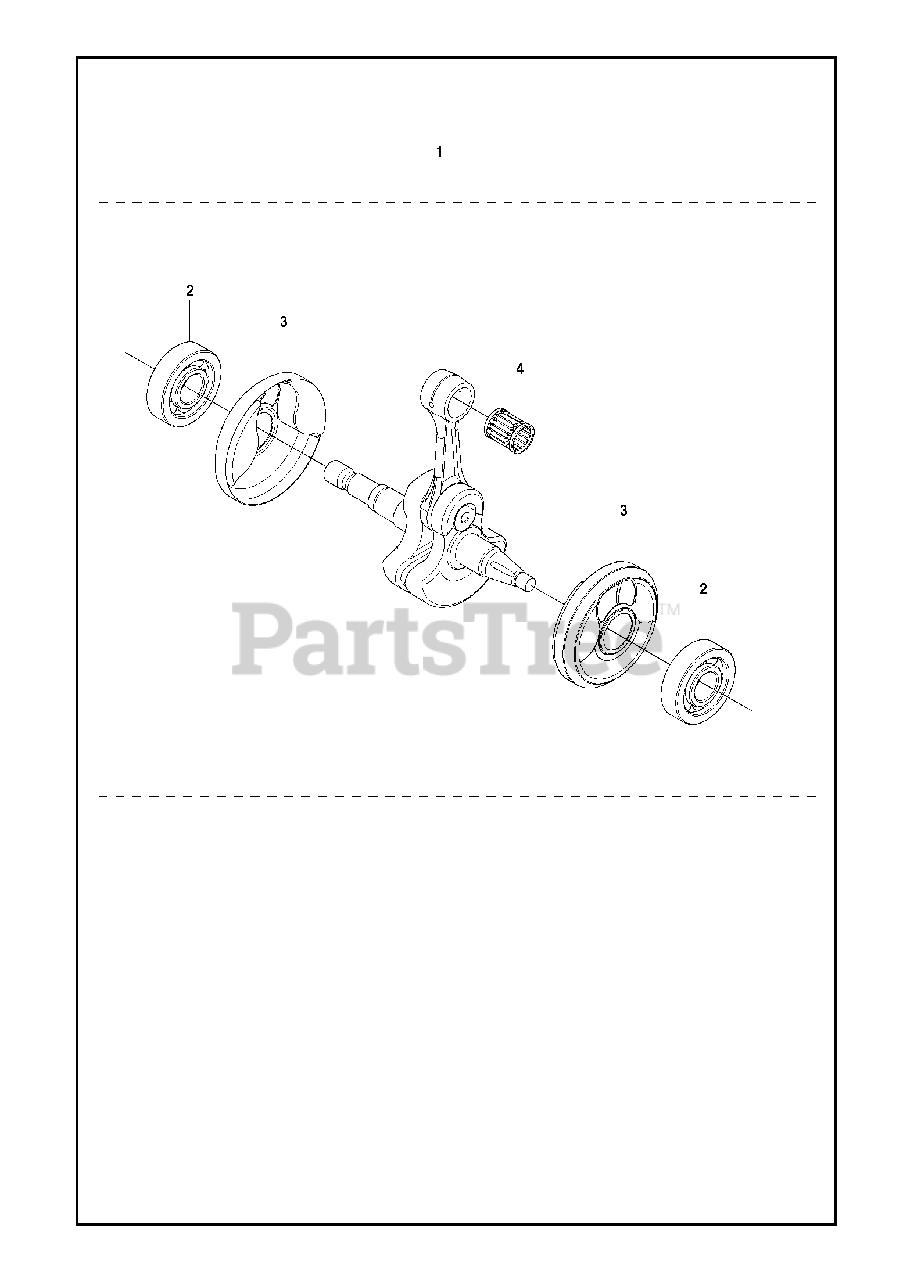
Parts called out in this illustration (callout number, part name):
1	CRANKSHAFT ASSY
2	BALL BEARING
4	NEEDLE BEARING
